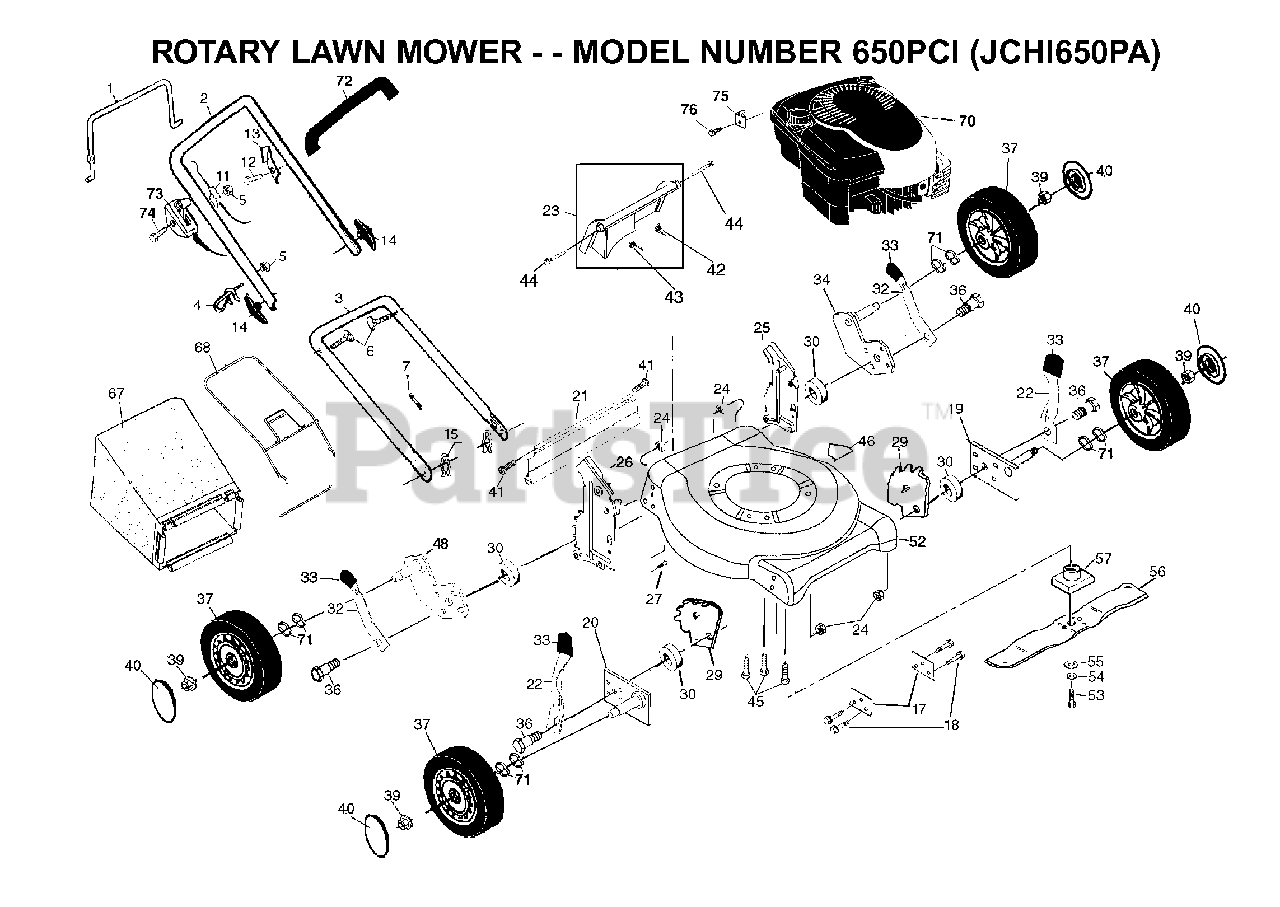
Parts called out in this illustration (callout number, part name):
1	CONTROL BAR
3	HANDLE.LOWER.GREY
4	ROPE GUIDE
5	NUT
6	HANDLE BOLT
7	TIE GUIDE
11	CABLE
12	TAPPING SCREW
13	BRACKET UPSTOP
14	HANDLE KNOB
15	HAIRPIN COTTER
17	SUPPORT BRACKET
19	AXLE ARM ASM (L)
20	AXLE ARM ASM
21	REAR DEFLECTOR, POULAN PR6N22
22	REPL BY 532 1683-60
24	NUT, LOCK 5/16-18
25	HANDLE BRACKET ASSEMBLY, LEFT
26	HANDLE.BRKT.ASSY.RIGHT.BLACK
27	SCREW
29	WHEEL BRACKET ADJUSTER
33	SELECTOR KNOB
36	SHOULDER BOLT
37	WHEEL ASMBLY FRONT
39	HEX FLANGE LOCKNT
40	CAP.HUB.ARC.SPOKE.8".LP
41	HINGE SCREW
45	BOLT 3/8-16X1-1/8
46	DECAL NLA
53	SCREW, HEX HD 3/8-24 X 1-3/8
54	LOCKWASHER
55	WASHER,HARDEN
56	21" PUSH BLADE
57	RP BLADE ADAPTOR
71	WAVE WASHER
72	GRIP.HANDLE.FOAM
73	THROTTLE CONTROL
74	SCREW 1/4-20 X 2.12
75	CABLE CLAMP(ENGINE)
76	SCREW.HEX.HEAD.WASHER.10-16
